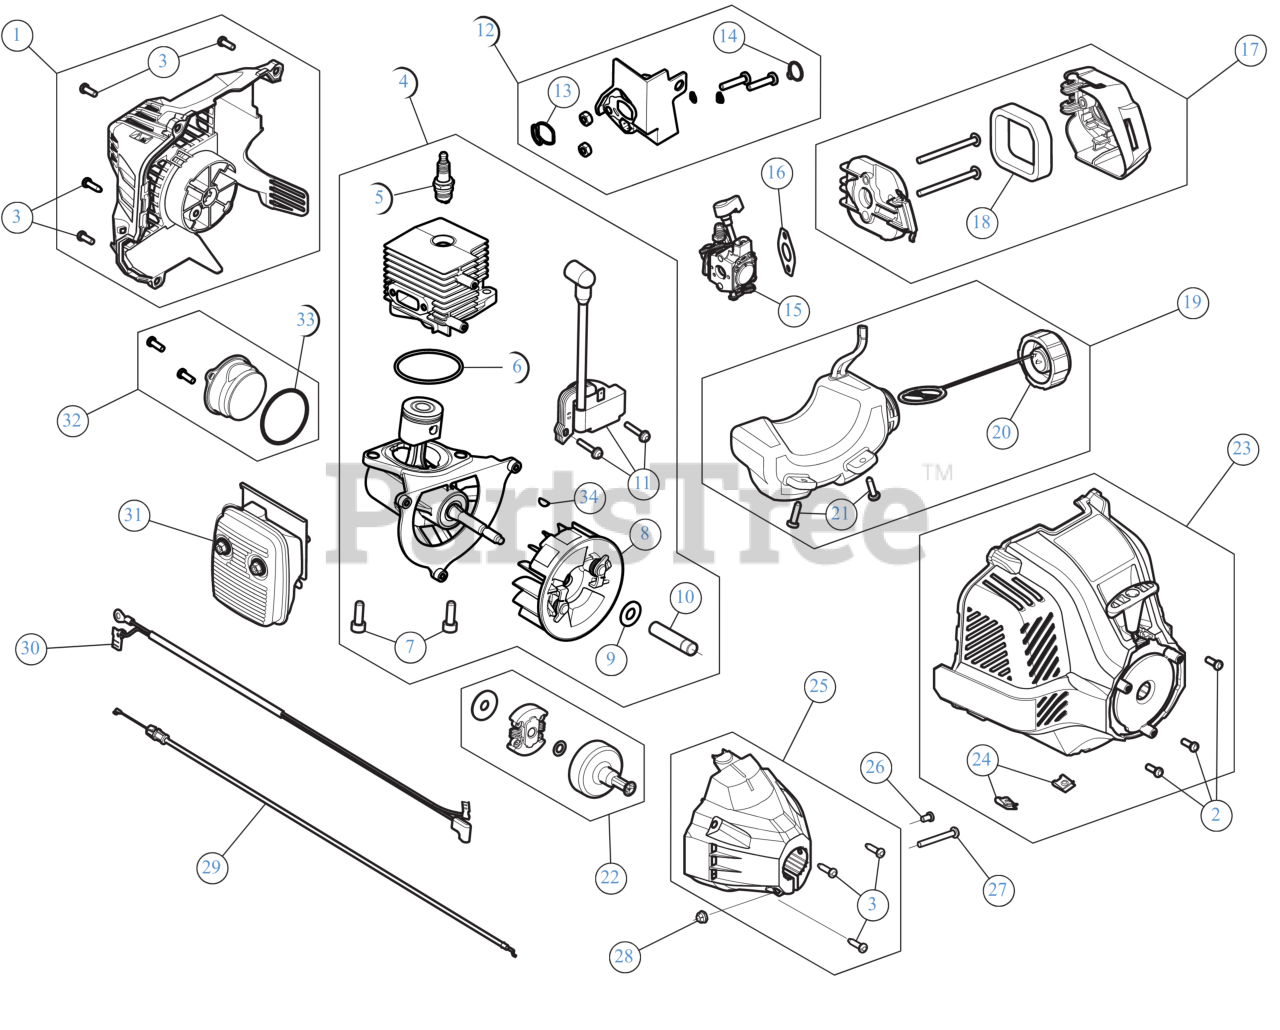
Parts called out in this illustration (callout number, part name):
1	REAR ENGINE COVER
2	SCREW #
3	SCREW 8-16 x 3/4
4	SHORT BLOCK 25cc
5	SPARK PLUG
6	O-RING SEAL CYLINDER
7	SCREW 5/16-18x3/4 T40
8	FLYWHEEL ASSEMBLY
9	BELL WASHER
10	SPACER :2.165"
11	MODULE
12	INTAKE ASSEMBLY
13	O-RING
14	CARBURETOR SEAL
15	CARBURETOR
16	GASKET CARB
17	AIR CLEANER
18	AIR FLITER
19	FUEL TANK ASSEMBLY
20	FUEL CAP ASSEMBLY
21	SCREW:10-6 x .75
22	SMALL CLUTCH ASSEMBLY W/SMALL DRUM
23	STARTER HOUSING (LIBERTY RED)
24	NUT, TINNERMAN U-T
25	CLUTCH COVER
26	SCREW, 8-32 x .312 P
27	SCREW
28	HEX NUT
29	THROTTLE CABLE
30	LEAD WIRES
31	MUFFLER
32	CRANKCASE COVER
33	O-RING SEAL CRANKCASE
34	WOODRUFF KEY #403-.125 x .375
